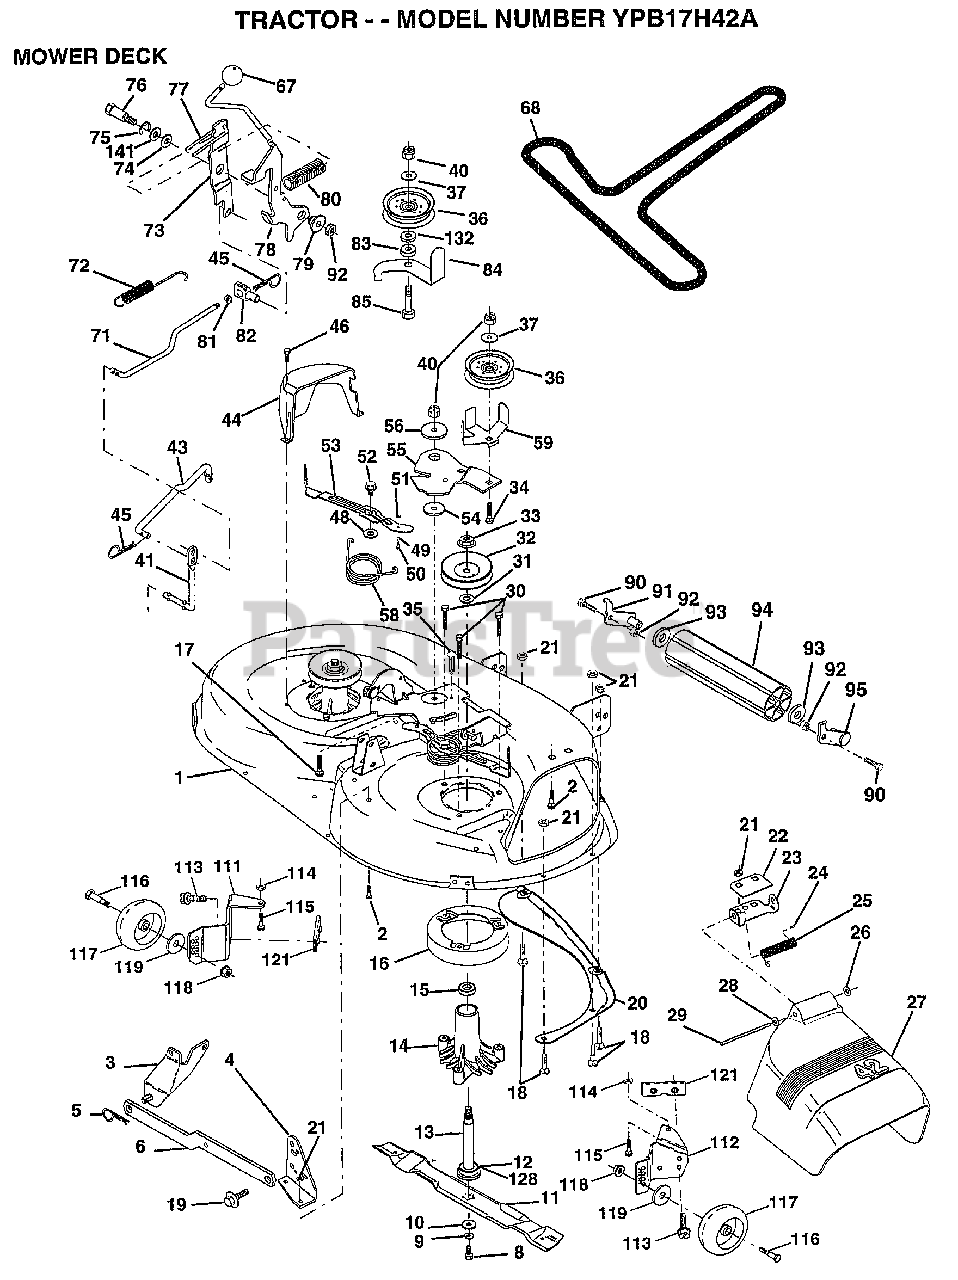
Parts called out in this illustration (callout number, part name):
1	"HOUSING ASSY.42"""
2	BOLT
3	BRKT ASM SWAY BAR
4	BRKT DECK SW BAR
8	BLADE BOLT
10	WASHER.HARD.BLADE
11	"BLADE.42"" HIPERF"
12	BEARING.BALL
14	HSG ASM MANDREL
15	BEARING
16	STRIPPER RND MWR
17	BOLT RDHD 3/8-16
18	BOLT
19	BOLT SHD 5/16-18
20	BAFFLE VORTEX 42
22	STIFFENER BRKT
23	DEFLECTOR BRKT
24	CAP-SLEEVE LT
25	SPRING TORSION
26	NUT PUSH M
27	DEFLECTOR.SHIELD
28	WASHER
29	HINGE ROD
30	"SCREW-THD ROLL,WA"
31	WASHER
32	PULLEY.MANDREL.42
34	BOLT
35	XMAS TREE FASTNER
36	FLAT IDLER PULLEY
37	WASHER
41	PIVOT ROD
43	ROD CLUTCH W/NIBS
44	GUARD MAND LH BLK
45	RETAINER M
46	SCREW.1/4-20X5/8
48	HARD SMALL WASHER
49	ROLLER ASM-CAM
50	SHOULDER BOLT
51	LOCKNUT
52	BOLT.SHLD.5/16-18
53	BRAKE PAD ARM ASM
54	HARDENED WASHER
55	ARM-IDLER
56	SPACER RETAINER
58	SPRING TORSN BRAK
59	GUARD IDLER TUV
67	KNOB.RD.7/16-14
68	BELT.V.T-PATH
71	ROD CLUTCH 38/42
72	RETURN SPRING
73	CLUTCH ARM SECOND
74	WASHER
75	RING
76	SHOULDER BOLT
77	SPRING KEEPER
78	LEVER.ASM.CLUTCH
79	BUSHING
80	SPRING.CLUTCH.MWR
82	TRUNION ADJ
83	WASHER
84	"KEEPER-BELT,FIXED"
85	BOLT
90	BOLT
92	NUT
93	WASHER
111	BRACKET.GWHL.LH.
112	BRACKET.GWHL.RH.
113	SCREW
116	BOLT M
117	WHEEL.GUAGE
118	LOCKNUT
119	WASHER
121	BRACKET.EXTRD.GWL
128	WASHER.FELT.
132	WASHER GT
141	WASHER .T
